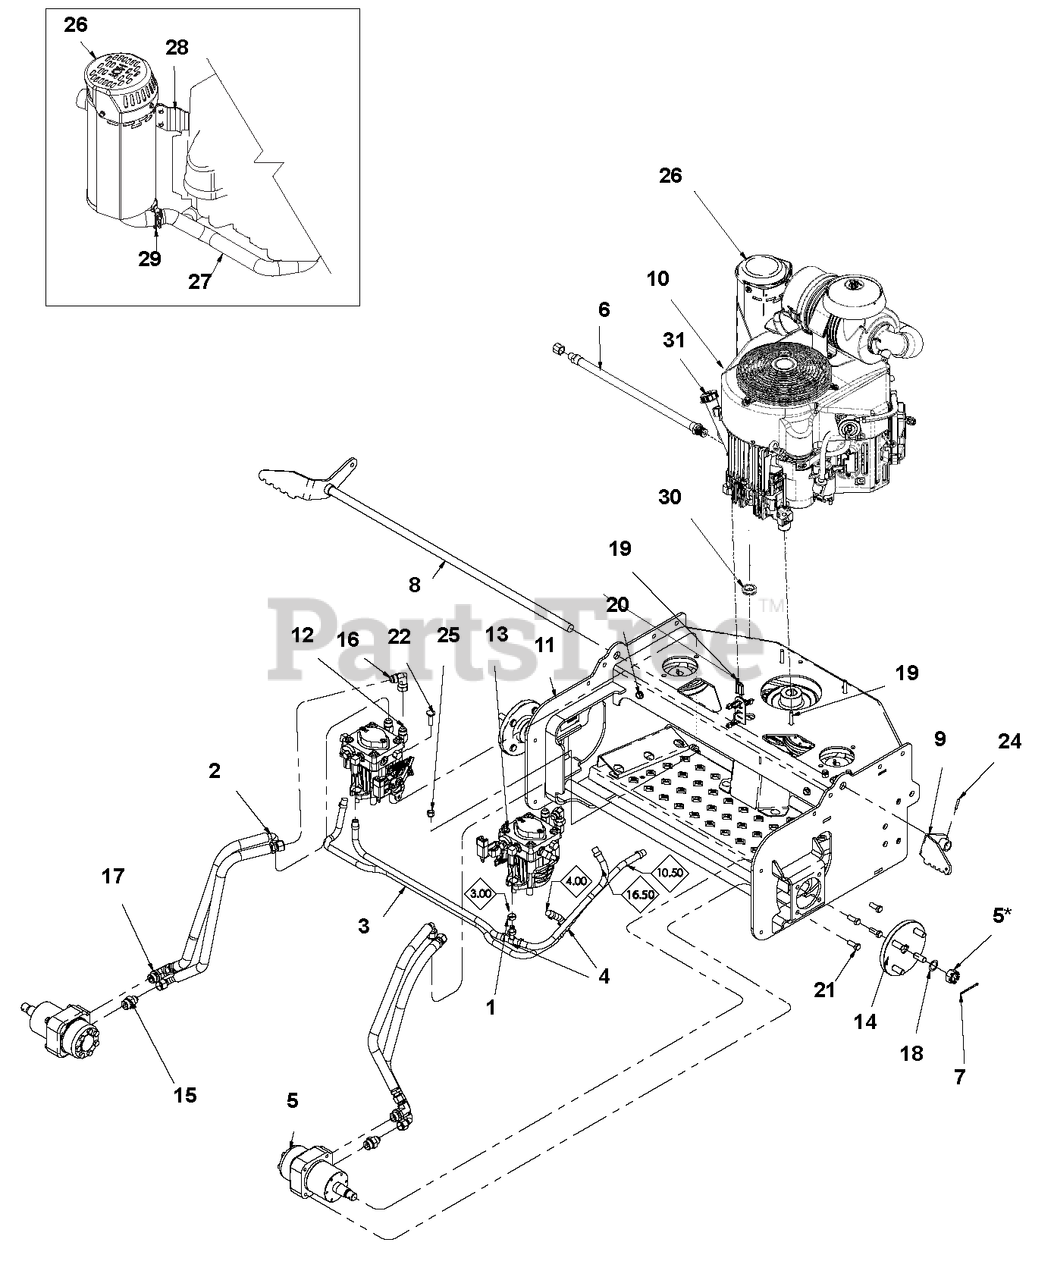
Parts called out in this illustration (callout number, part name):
1	HOSE CLAMP
2	HOSE, HIGH PRESSURE
3	HOSE, 3/8 SAE30R7 FUEL & OIL
4	TEE FITTING
5	MOTOR, HYD WHEEL
6	DRAIN, M20 OIL
7	@PIN-CTR .125X2.00 YWZC
8	WLDT, BRAKE SHAFT
9	WLDT, RH BRAKE ARM
10	ENGINE, KAWASAKI FX600
11	WLDT, DECK FRAME W/DCALS ARIEN
12	ASSEMBLY, HYD PUMP
13	ASSEMBLY, HYD PUMP
14	ASSY, REAR WHEEL HUB
15	ADAPTER, HYD ST 7/8 "O" TO 3/4
16	ADAPTER, 3/4 FESW X 3/4MJICX90
17	ADAPTER, 8MJ-10MB90
18	BUSHING, MACH .750X1.25X.048 Y
19	BLT-HEX.38-16X1.25FTHG5 EP80YZ
20	BOLT, 3/8-16X1.00 FGH 8 Y
21	@BLT-HEX .38-16X1.00 GR5 YWZC
22	@BLT-RDHDSQNK .38-16X1.25 G5YZ
23	@NUT-LK-NYL .312-18 YWZC
24	PIN-ROLL .156X1.00
25	@NUT-LK-NYL .38-16 YWZC
26	MUFFLER, KAWASAKI FX OFS STD
27	MANIFOLD, EXH KAWASAKI FX STD
28	BRACKET, MUFFLER KAWI OFS STD
29	CLAMP, MUFFLER KAWI FX STD
30	GROMMET:RUB:.88IDX1.38ODX.14GR
31	CAP, FILLER, OIL
